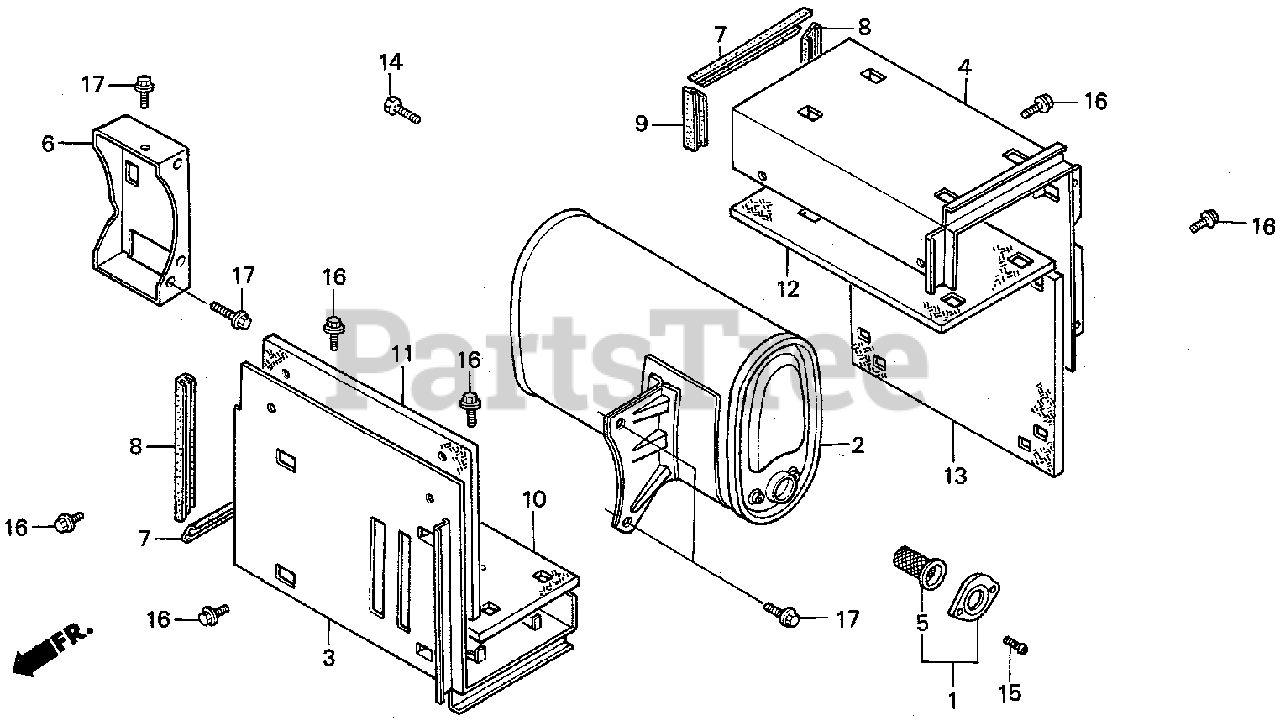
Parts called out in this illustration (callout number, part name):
1	ARRESTER SET, SPARK
3	DUCT, MUFFLER (LOWER)
4	DUCT, MUFFLER (UPPER)
5	ARRESTER, SPARK
6	STAY, MUFFLER
7	SEAL, MUFFLER DUCT (A)
8	SEAL, MUFFLER DUCT (B)
9	SEAL, MUFFLER DUCT (C)
10	INSULATOR A, MUFFLER DUCT (LOWER)
11	INSULATOR B, MUFFLER DUCT (LOWER)
12	INSULATOR A, MUFFLER DUCT (UPPER)
13	INSULATOR B, MUFFLER DUCT (UPPER)
14	BOLT, HEX. (8X28)
15	SCREW, PAN (6X10)
16	BOLT, FLANGE (6X12)
17	BOLT, FLANGE (8X16)
